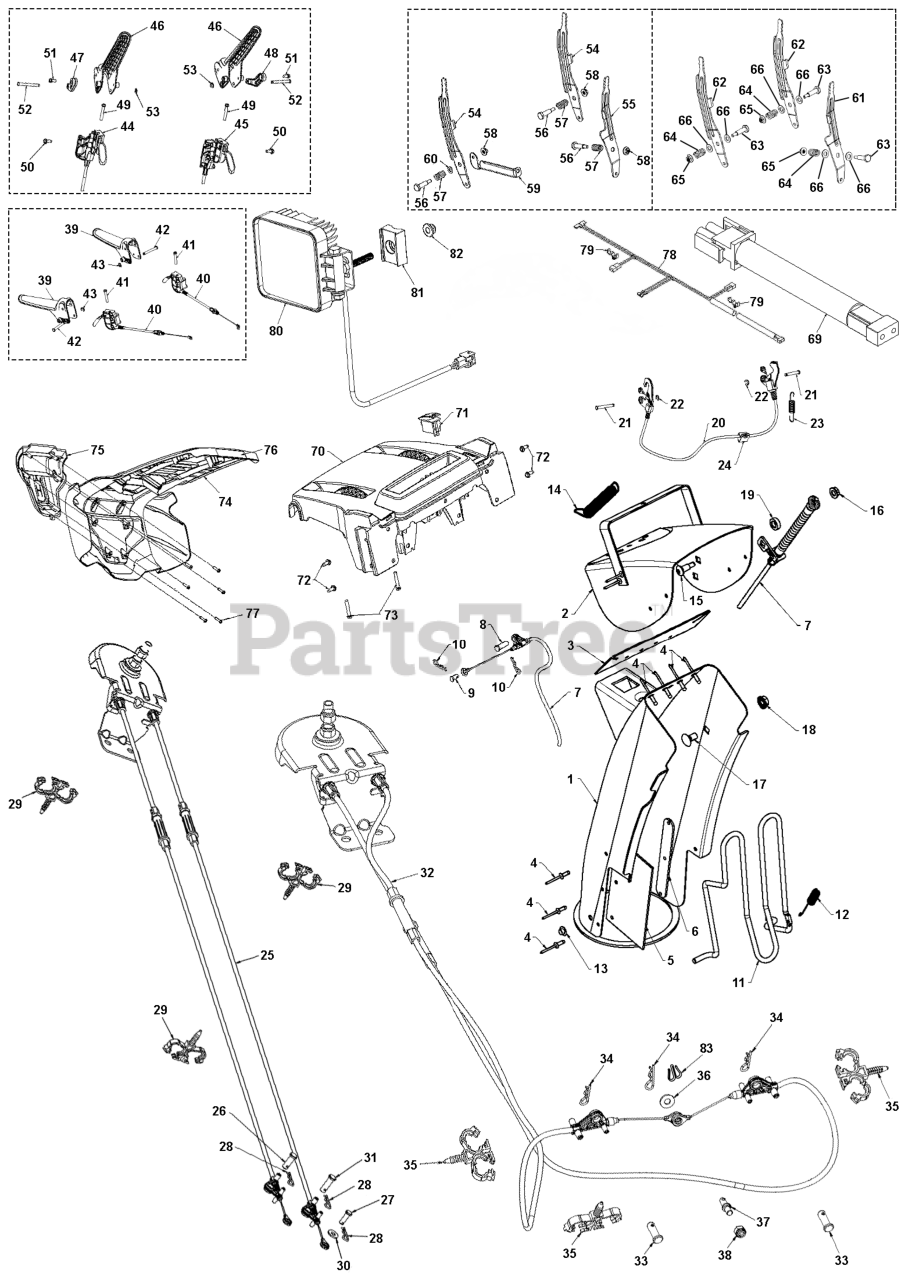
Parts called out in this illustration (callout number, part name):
1	CHUTE.WELDMENT.SNOW.ORANGE
1	ASM.CHUTE/DEFLECTOR.668
2	DEFLECTOR.WELDMENT.PNT.ORANGE
3	SEAL.DEFLECTOR
4	RIVET BLIND
5	SHIELD.SNOW.CHUTE
6	STRAP.SHEILD.RETAINER
7	CABLE.CONTROL.CHUTE.DEFLEC
7	Controls
7	CABLE CONTROL.CHUTE.DEFLECTOR.
7	CABLE CONTROL.CHUTE.DEFL.BOWDE
8	PIN CLEVIS 5/16X.875
9	PIN CLEVIS .25 X .31
10	HAIRPIN.SOFT.ZINC.059X1.125
11	ROD.GUARD.CHUTE (2 2)
11	GUARD ROD CHUTE GUARD SHORT CL
12	SPRING.CHUTE.GUARD
13	PAL NUT PM
13	NUT
14	SPRING.DEFLECTOR.REM.CHUTE
15	BOLT CAR BLK 5/16-18 X 5/8
15	BOLT.CARR.W.3125 SHLDR..25-20
15	BOLT SHOULDER 1/4
16	NUT.HEX.LRG.FLANGE.1/4-20.LOCK
17	BOLT CAR BLK 5/16-18 X 5/8
18	NUT.HEX.FLANGE.LOCK.5/16-18
18	Hardware
19	WASHER.NYLON.326 X.625 X.205
20	CABLE.INTERLOCK.DSST
20	CABLE INTERLOCK CONTROL ACETAL
21	PIN.GROOVED
23	SPRING RETURN_INTERLOCK_DSST
24	CLIP.CABLE.BLK
25	CABLE ASSY CONTROL
25	CABLE.ROTATOR.ASSEM.SNOW
26	PIN CLEVIS 5/16X.875
27	PIN.CLEVIS
28	HAIRPIN.SOFT.ZINC.059X1.125
29	CLIP.CONDUIT.DOUBLE LOOP
30	WASHER FLAT_.250 X .625 X .06
31	PIN CLEVIS CLEVIS
31	PIN CLEVIS 5/16 X 1.0 L
32	Chutes
33	PIN CLEVIS 5/16X.875
34	HAIRPIN.SOFT.ZINC.059X1.125
35	CLIP.CONDUIT.DOUBLE LOOP
36	WASHER FLAT_.250 X .625 X .06
37	Pins
38	NUT HEXAGON 1/4-20 ST ZPB
39	LEVER CONTROL DSST OPP MPP
40	CABLE.CONTROL.PS.OPP.SNOW
40	CONTROL UNIT ASSEMBLY_LEVER_PI
41	SCREW HEX WASH MACH BLK 10-24
42	PIN.GROOVED
43	E-RING
44	CABLE.POWER STEERING.LHS
44	HANDLE.LEVER.PIVOT.LHS.BLACK
45	HANDLE.LEVER.PIVOT.RHS.BLACK
45	CABLE.POWER STEERING.RHS
46	LEVER CONTROL DSST OPP MPP
47	LEVER.CABLE.ARM.LHS.BLACK
48	LEVER.CABLE.ARM.RHS.BLACK
49	SCREW HEX_WASH_13-16 X 1.50_H
50	SCREW 14-20 X 5/8
51	SCREW.HWH.13-16X.50
52	PIN.GROOVED
53	E-RING
54	LEVER.CONTROL.SPEED/DEFLEC.BLK
55	LEVER.CONTROL.CHUTE.ROTATON.BL
56	BOLT SHOULDER_HEX
56	BOLT SHOULDER_HEX HD_1/4-20_3/
57	SPRING.COMPRESSION.82LBS
58	NUT HEX_LRG FLG_1_4-20_LOCK
59	BRACE.SUPPORT.SPEED.BLACK
60	WASHER.FLAT.625 X .375 NYLON
61	Levers
62	LEVER.CONTROL.SPEED/DEFLEC.BLK
63	BOLT SHOULDER_HEX HD_1/4-20_3/
64	SPRING.COMPRESSION.82LBS
65	NUT HEX_LRG FLG_1_4-20_LOCK
66	WASHER, NYLON FRICTION
69	Harnesses
69	HARNESS WIRE.LIGHT AND GRIPS
70	CONSOLE BASE MULTI CONTROL
71	SWITCH HEATED GRIP BLK
72	SCREW 14-20 X 5/8
73	SCREW HEX_WASH_13-16 X 1.50_H
74	Consoles
75	Consoles
76	Decals
77	SCREW
78	Harnesses
79	PUSH CLIP
80	LED LIGHTS
81	MOUNTING BRACKET LIGHT MOUNTIN
82	NUT HEXAGON FLANGE 5/16-18 ST
83	GSPW Retainers
